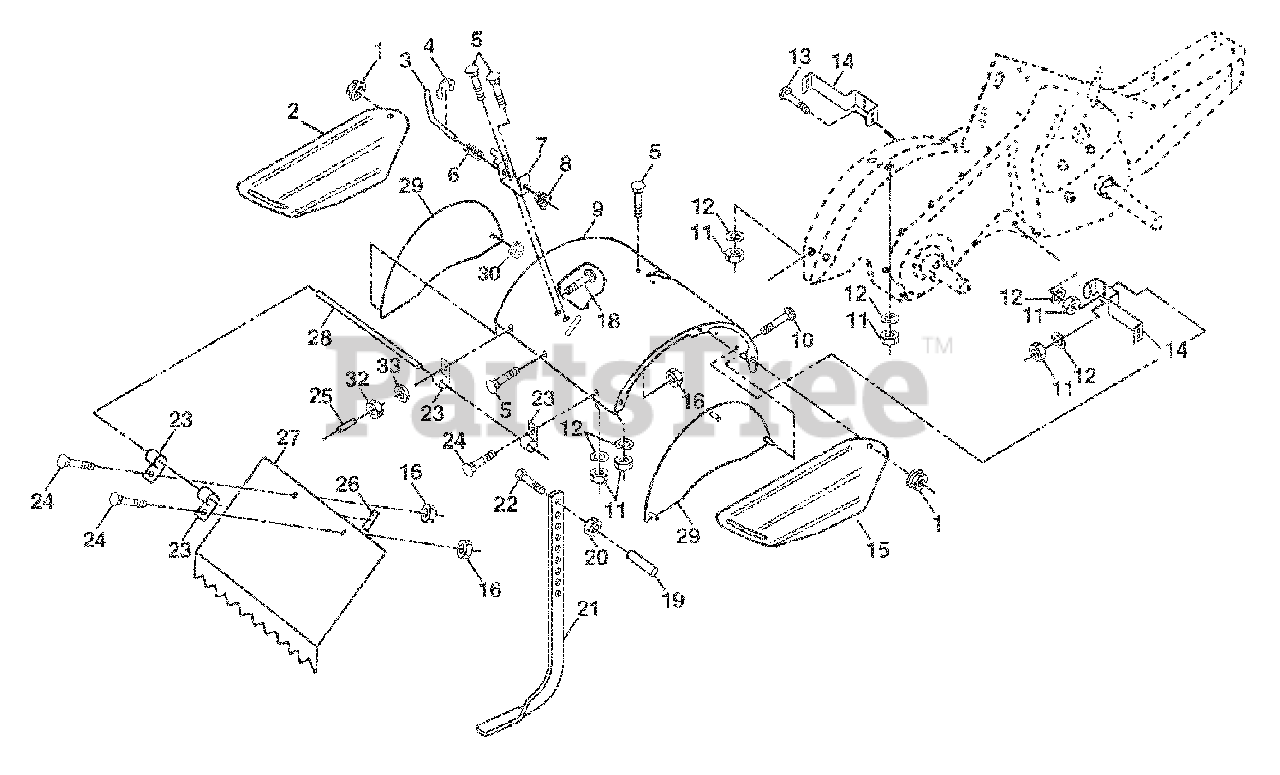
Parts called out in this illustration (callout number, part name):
1	Nut, Lock Hex Flange 5/16-18
2	Shield, Side, Outer L. H.
3	Pin, Stake, Depth
4	Ring, Klip
5	Bolt 5/16-18 Unc x 1
6	Spring
7	Bracket, Latch
8	Spring, Depth Stake
9	Shield, Tine
10	Bolt 5/16-18 x 3/4 ZNC
11	Nut, Hex 5/16-18
12	Washer, Lock 5/16
13	Bolt, Carriage 5/16-18 x 1-1/4
14	Bracket, Shield Tine
15	Shield, Side, Outer R.H.
16	Nut, Hex Flange 1/4-20 UNC
18	Bolt, Carriage 1/4-20 x 1-1/4 Gr.
19	Grip
20	Nut, Hex 3/8-16
21	Stake, Depth
22	Bolt, Hex 3/8-16 x 2
23	Hinge
24	Bolt, Carriage 1/4-20 x 1/2 Gr. 5
25	Cap, Vinyl
26	Pad, Idler
27	Shield, Leveling
28	Pin, Hinge
29	Shield, Side
30	Locknut, Flange 5/16-18
32	Nut Fin Hex 1/4-20 UNC
33	Washer Lock Hvy Helical 1/4
